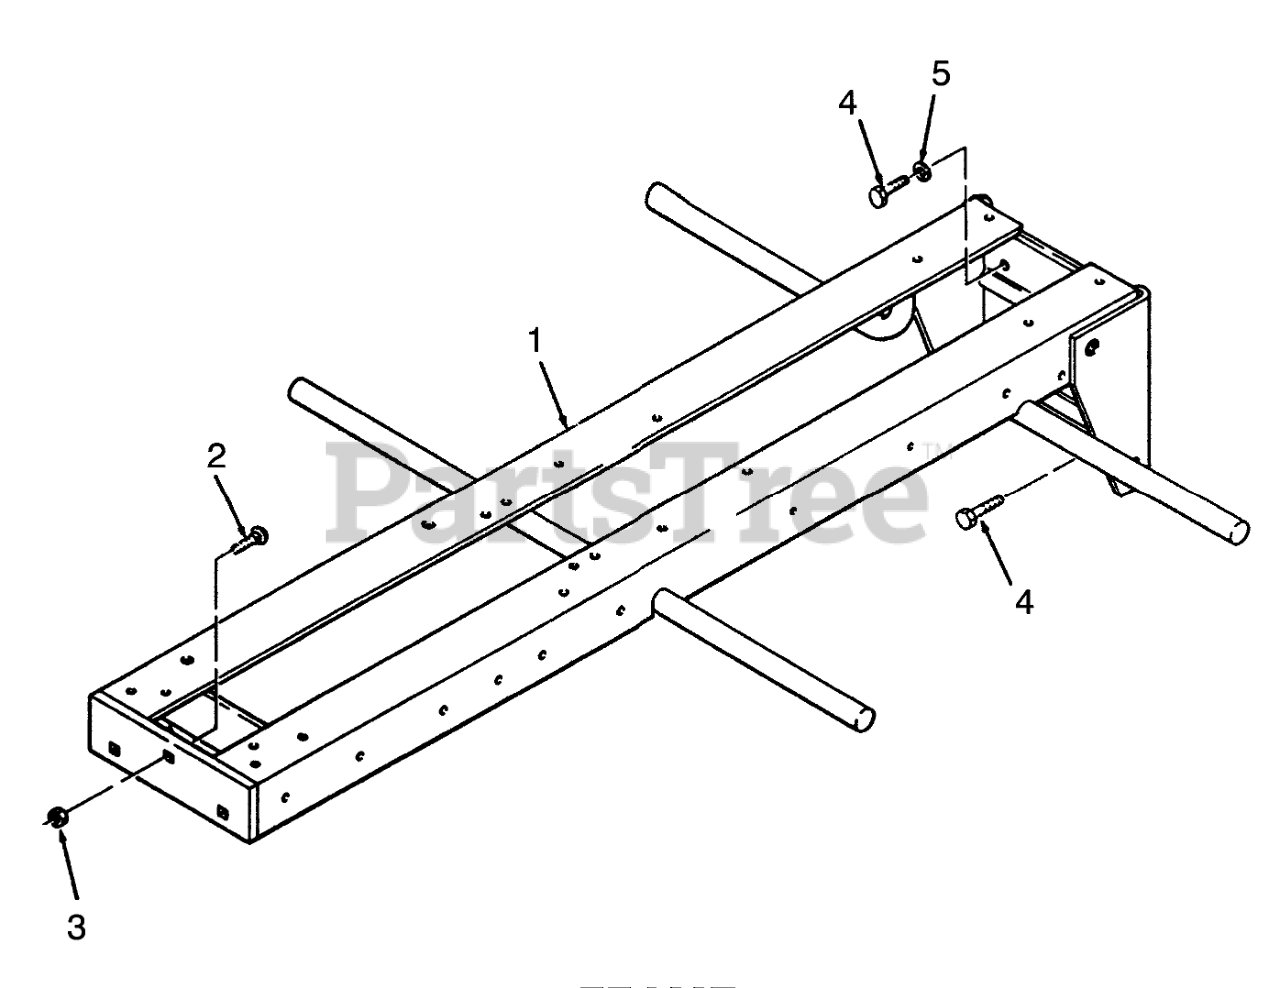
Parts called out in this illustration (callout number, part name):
1	WELD FRAME R
2	BOLT-CARR
3	NUT-LOCK, NI
4	SCREW-HH
5	WASHER-LOCK
